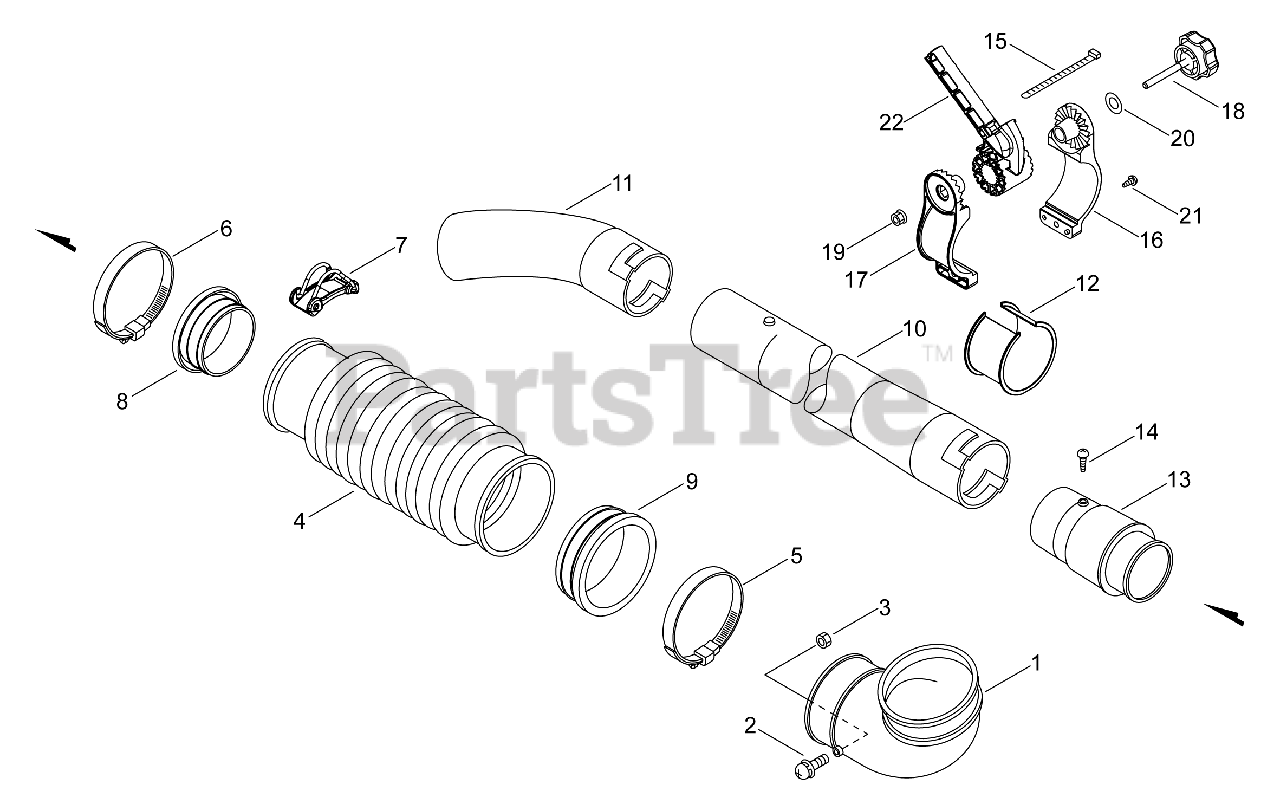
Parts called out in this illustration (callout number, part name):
1	TUBE, BLOWER - ELBOW
2	SCREW 5×14
3	NUT M5
4	TUBE, FLEXIBLE
5	CLAMP - BAND
6	CLAMP 58.7 MM / 82.5 MM
7	CLIP, CABLE
10	TUBE, BLOWER - STRAIGHT
11	TUBE, BLOWER - CURVED
13	TUBE, BLOWER - SWIVEL
14	SCREW, TAPPING
15	STRAP, TIE
16	BRACKET, HANDLE - RIGHT
17	BRACKET, HANDLE - LEFT
18	KNOB, SCREW
19	NUT, FLANGE M6
21	SCREW, TAPPING 5×20
22	BRACKET, THROTTLE
